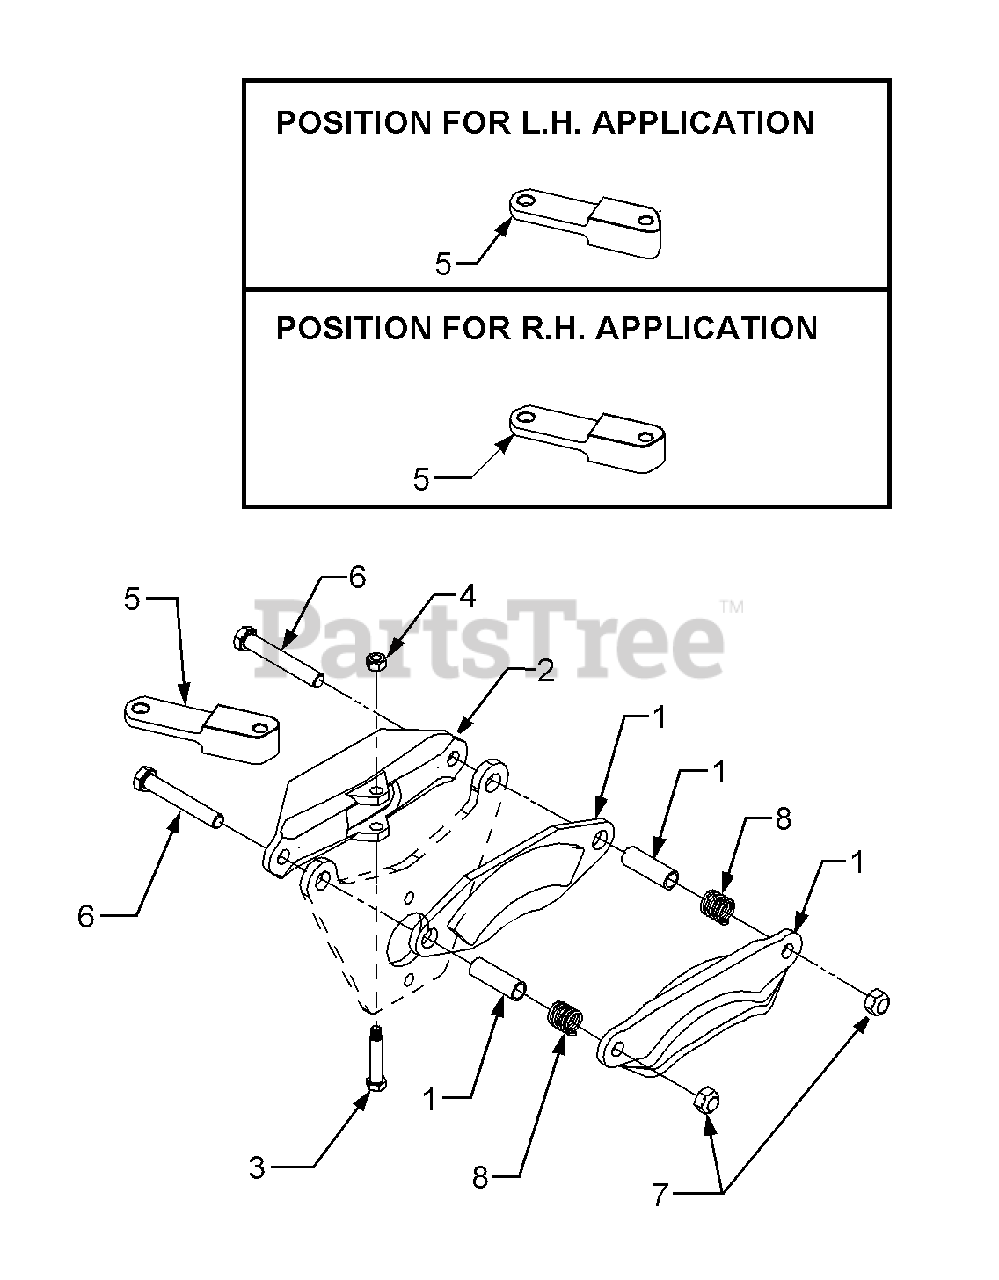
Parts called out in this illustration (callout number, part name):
1	Pad Kit, Brake
2	Bracket, Brake Actuator
3	Screw, Shoulder
4	Nut, Hex Top Lock, 1/4-20
5	Arm, Brake Actuator
6	Screw, Hex Cap, 3/8-24 x 2.5 GR5
7	Nut, Hex Lock, 3/8-24
8	Spring, Compression
